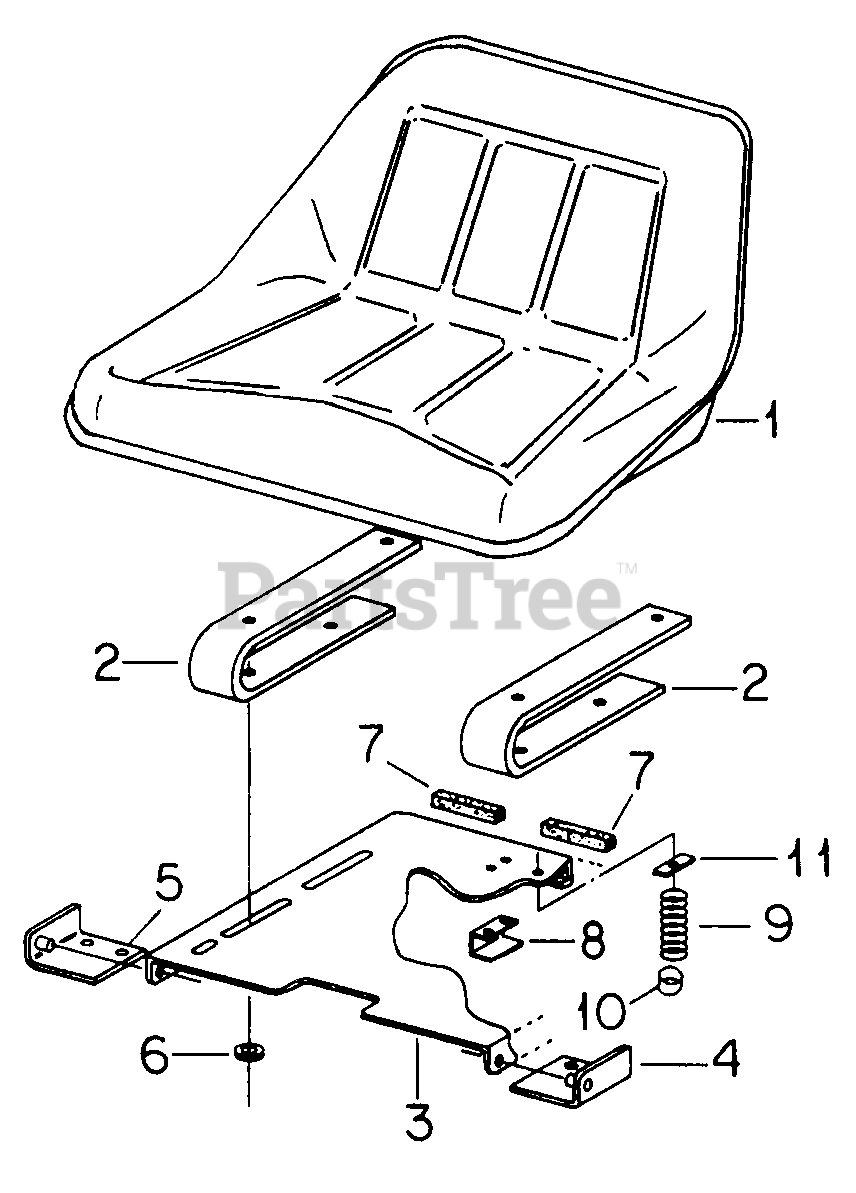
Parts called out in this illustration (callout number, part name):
1	Seat Assy
2	Spring, Seat
3	Cover
6	Washer, 11/32 X 1-1/2 X 11 Ga
7	Bumper, Seat Support Adhesive, Loctite #495
8	Channel, Switch Actuator
9	Spring, Seat Switch
10	Cap, Spring
11	Nut, Spring
